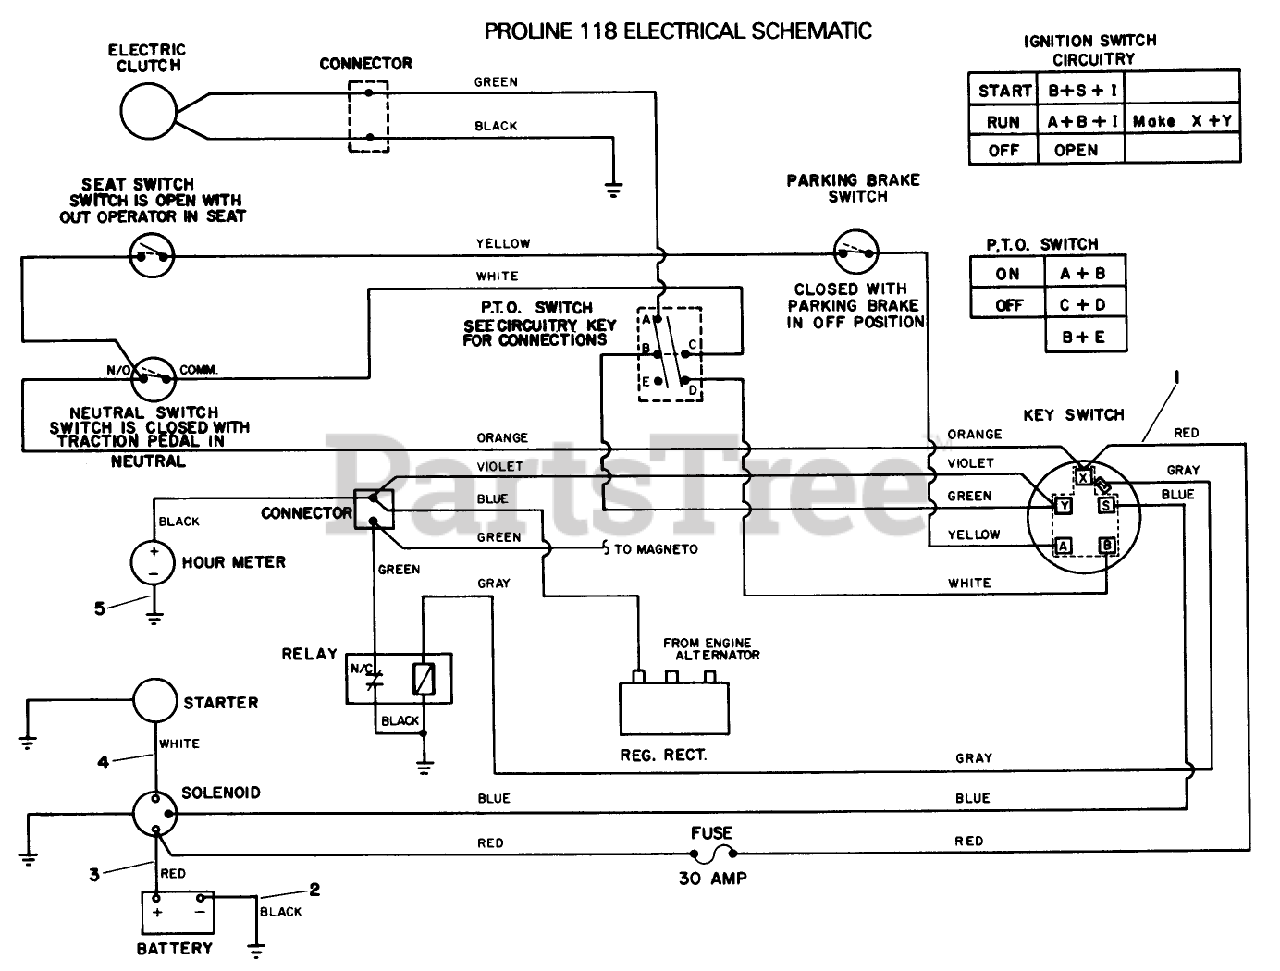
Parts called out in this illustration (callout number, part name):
1	WIRE HARNESS
2	BATTERY/GROUND WIRE
3	WIRE ASM
4	WIRE ASM
5	WIRE ASSEMBLY
